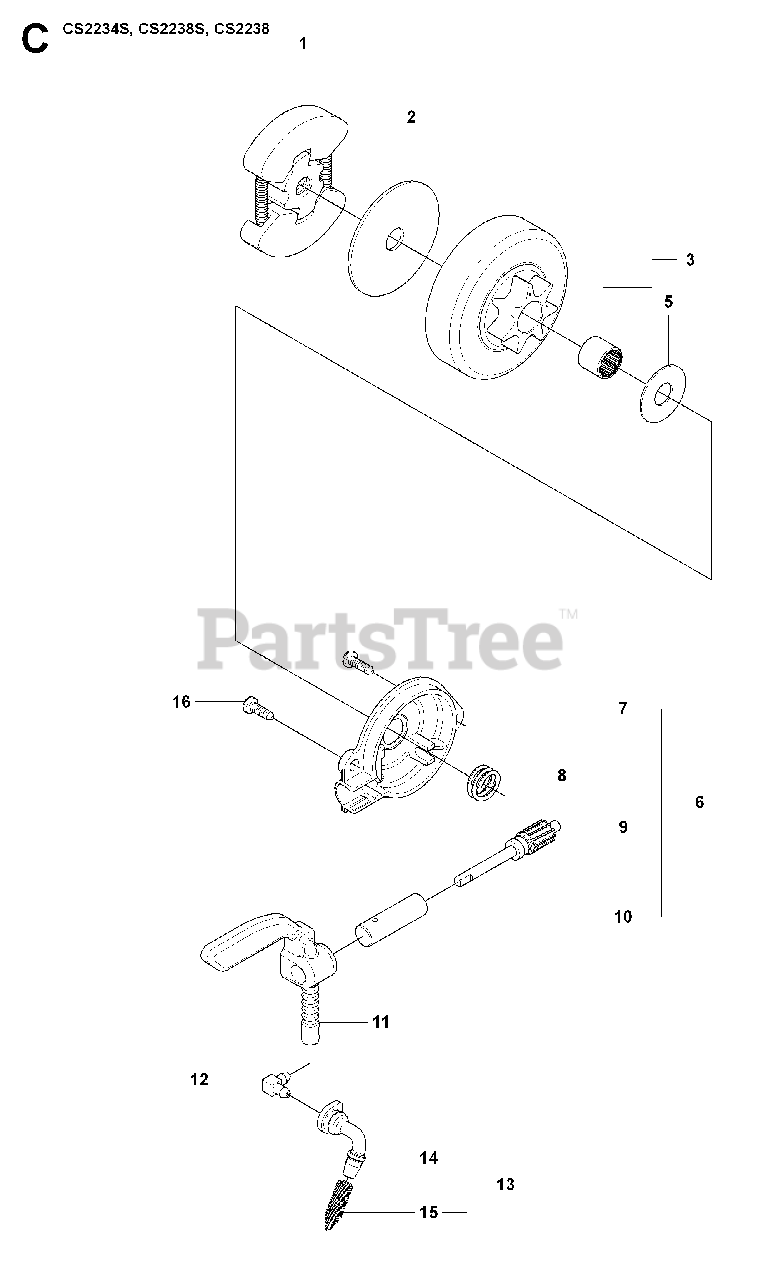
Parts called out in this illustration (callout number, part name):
1	CLUTCH ASSEMBLY
2	FRICTION DISC,CLUTCH 36/41
3	CLUTCH DRUM ASSY
3	ASSY CLUTCH DRUM .325"
5	DUST COVER 36/41
6	ASSY OIL PUMP
7	ASSY OIL PUMP
8	WORM GEAR
9	PLUNGER & GEAR
10	PUMP
11	OIL BLOCK
13	PICK UPS ASSY OIL TANK
15	SCREEN/FILTER
